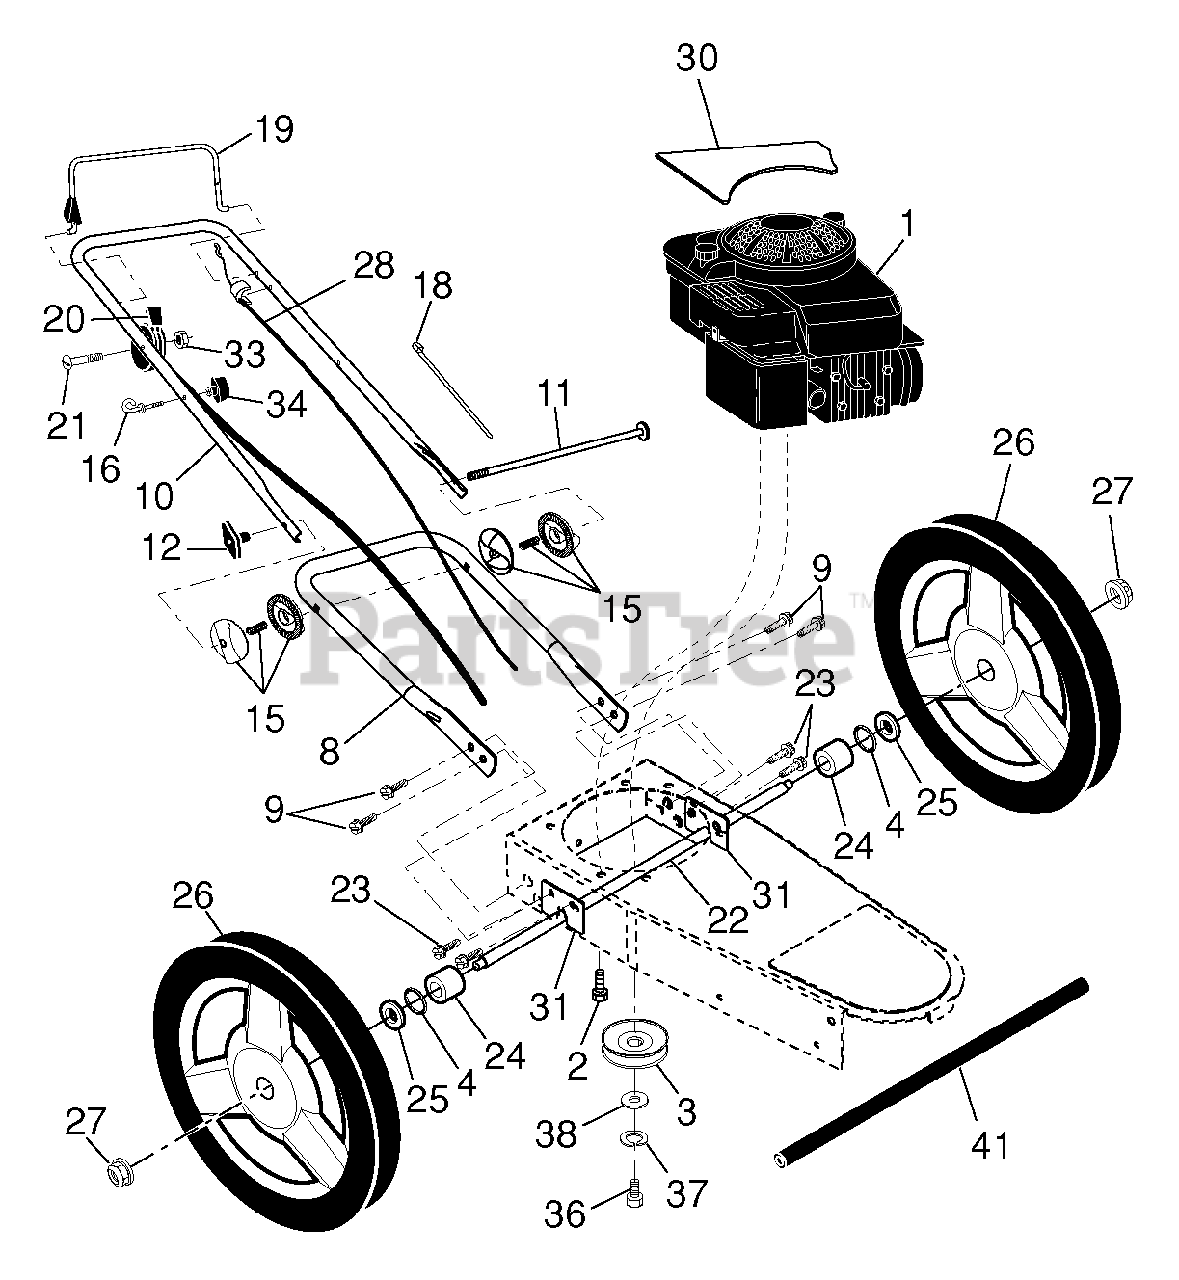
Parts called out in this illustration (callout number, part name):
2	BOLT 3/8-16X1-1/8
3	PULLEY, ENGINE
4	O-RING..070X.487.NEOPRENE
8	HANDLE.LOWER.STRING.TRIMMER.GR
9	BOLT.HEX.HD.WASHER.5/16-18X.75
10	HANDLE.UP.STRING.TRIMMER.GREY
11	BOLT.HANDLE.WHEELED.TRIMMER
12	KNOB, DEFLECTOR
15	ADJSTR.ASSEM.HANDLE.WHLD.TRIMM
16	GUIDE.ROPE.BLK.ZINC.CHROM
18	TIE GUIDE
19	BAIL.ARM.ASM.TRIMMER.BLK/ORNG
20	RP CONTROL.THRO.S-TRM.SNPIN.BS
21	SCREW.PAN.HEAD
22	AXLE.TRIMMER
23	BOLT.HEX.HD.WASHER.5/16-18X.75
24	SPACER.AXLE.STRING.TRIMMER
26	WHEEL.12 X 1.75 CFH3SPK.RAD3
27	NUT.HEX.FLANGE.3/8-16.LOCKNUT
28	CABLE.DRIVE.TRIMMER
30	DECAL.TRIMMER.WARNING.CE
31	BRACKET, AXLE
33	NUT
34	T-KNOB.NEW ROPE GUIDE
36	SCREW, HEX HD 3/8-24 X 1-3/8
37	LOCKWASHER
38	WASHER,HARDEN
41	TUBE.AXLE.TRIMMER.BLACK
